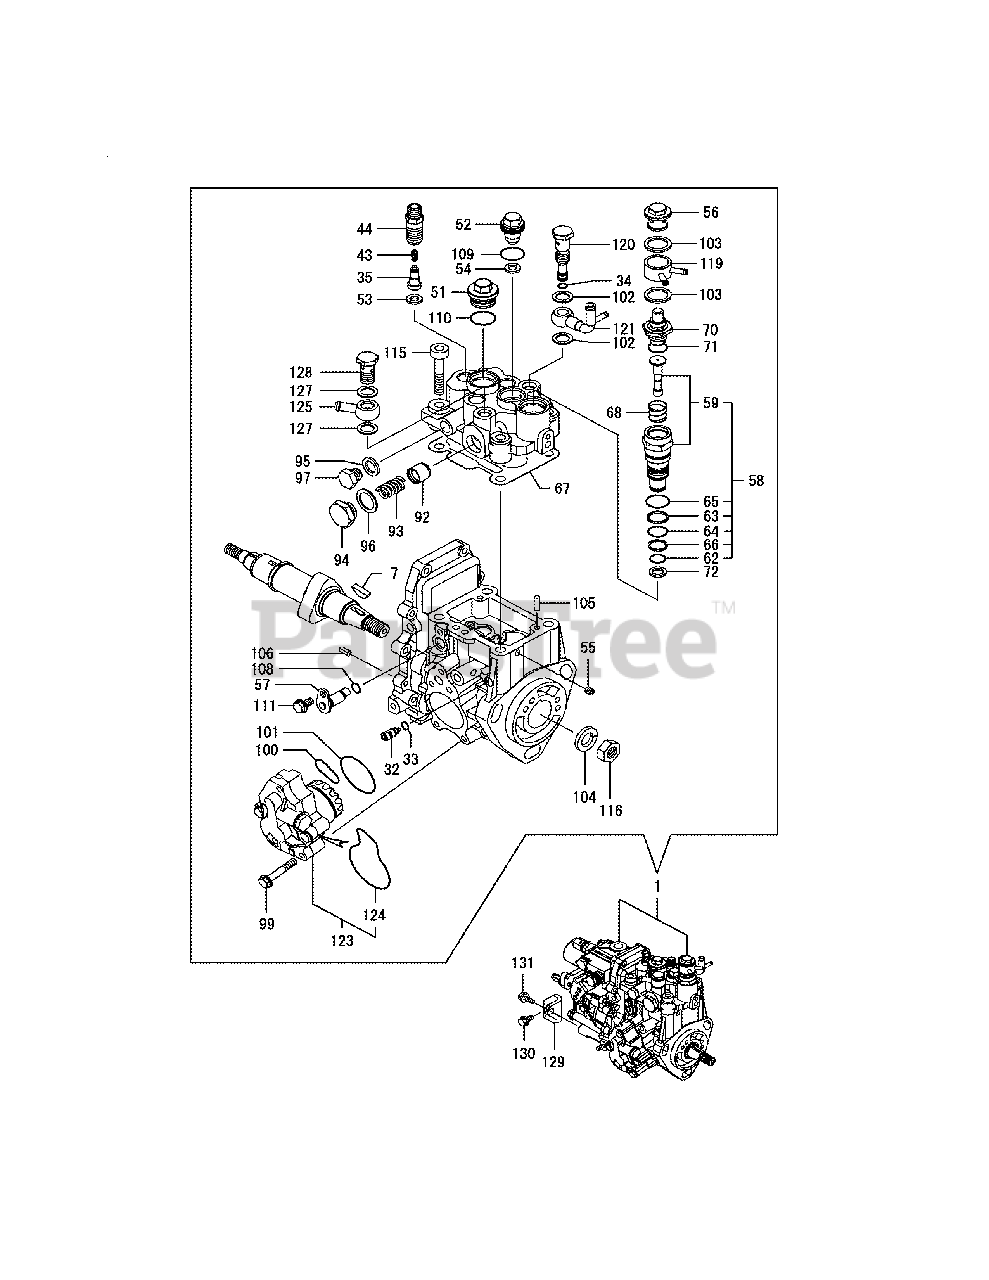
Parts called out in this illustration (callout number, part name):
1	INJECTION PUMP ASSY
7	KEY, WOODRUFF 4X16
35	VALVE ASSY, DELIVERY
44	HOLDER, DELIVERY
53	GASKET
54	GASKET
56	PLUG, WATER PUMP
59	TIMER CMP
66	RING, BACKUP T2 P 15
70	ELEMENT, THERMO
72	PACKING, TIMER
95	SEAL WASHER 12
96	SEAL WASHER 18
97	PLUG M12, HEX.
102	SEAL WASHER 12
103	SEAL WASHER 18
104	SPRING WASHER 14
105	PARALLEL PIN 5X14
106	SPRING PIN 5X10
108	O-RING 1A P-7.0
111	BOLT 6X 10 PLATED
116	LOCK NUT M14 PLATED
119	JOINT, COOLING WATER
123	PUMP ASSY, FEED
124	O-RING, FEED P INNER
125	JOINT 12, PIPE
127	SEAL WASHER 12
128	JOINT BOLT 6,PIPE
130	BOLT M 8X 16 PLATED
131	BOLT M 8X 20 PLATED
